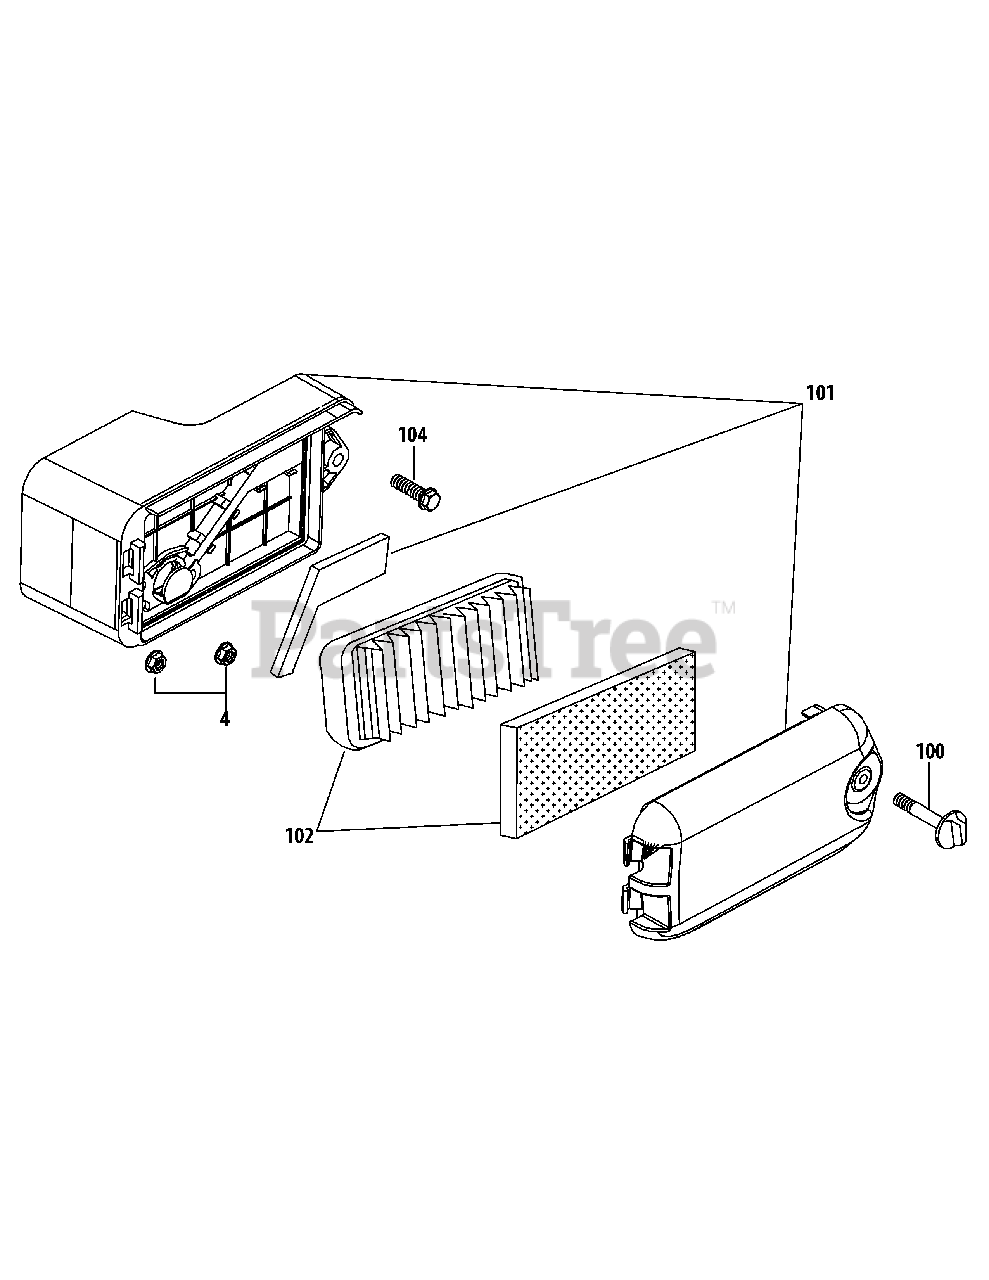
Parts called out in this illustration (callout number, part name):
4	Nut M6X10Mm
100	Air Filter Cover Thumb Screw
101	Air Cleaner Housing Assy Comp
102	Air Cleaner Kit
104	Bolt M6X30
